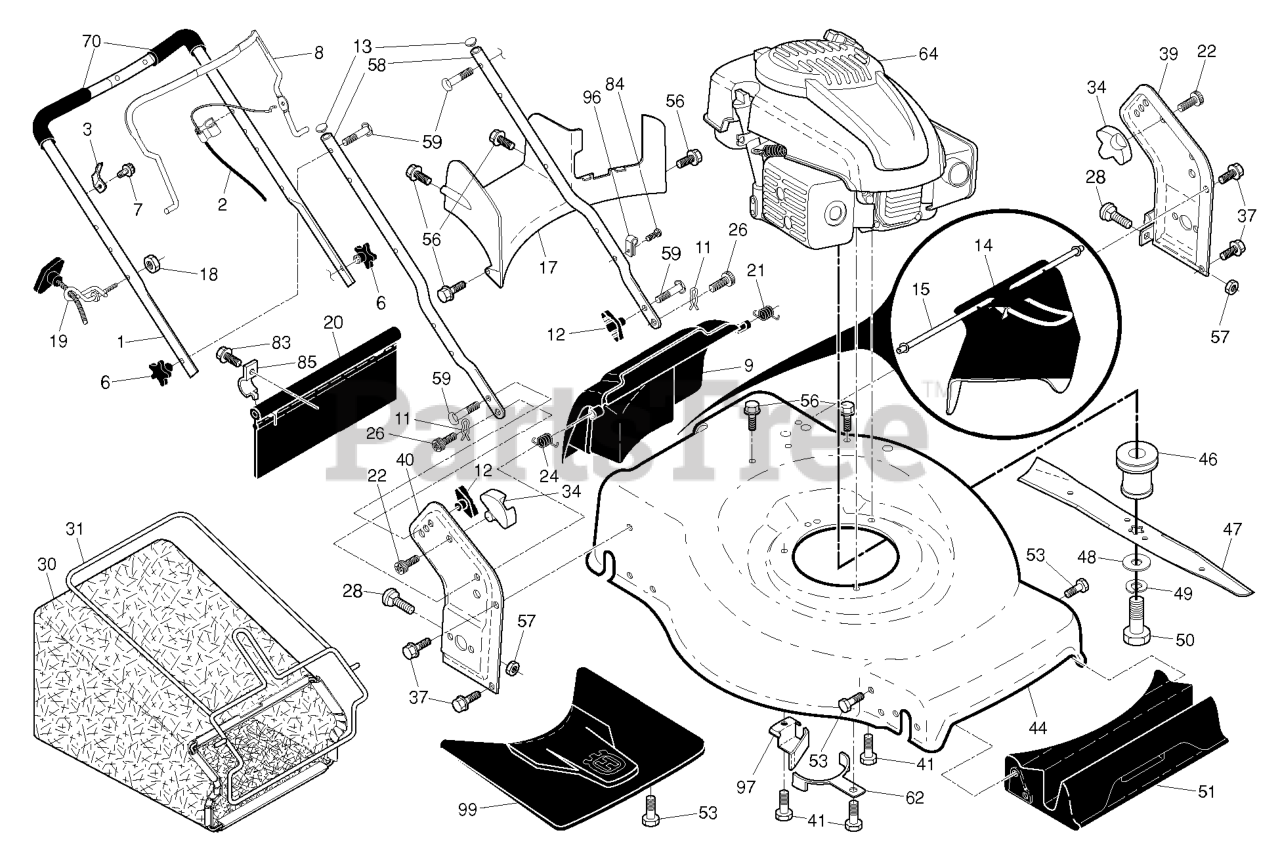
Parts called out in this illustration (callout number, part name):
1	HANDLE.ASM.GRY.W/GRIP
2	CABLE.MZR.RGD.KOHLER.STRT
3	BRACKET.UPSTOP.RT
6	KNOB.HANDLE.PLASTIC.STAR.BLACK
8	BAIL.MZR.EZ2.DSTR.22+.ORG.E
9	DOOR.REAR.ASM.22+.HUSQ.FG/RGD
11	COTTER.HAIRPIN.DOOR/HANDLE.PIV
12	KNOB.WING.PLASTIC.BLACK
12	HANDLE.KNOB.BLACK
13	PLUG.PLASTIC.7/8".14-20.GAUGE
14	DEFLECTOR.CHUTE.22+REAR
15	HANDLE DEFLECTOR.22+REAR
17	RP.BAFFLE.REAR.22+.RGD.PL
18	NUT
19	RB GUIDE.ROPE.STD.BLK.ZIN WSL
20	SKIRT.REAR.22PLUS.RGD.LW(2 2MC
21	SPRING.LH.BLACK
22	SCREW.PAN.HEAD.#10
24	SPRING.RH.GRAY
26	SCREW,DOOR/HANDLE.PIVOT
28	BOLT
30	GBAG.A3610247T.SILV.HUSWT.BLUE
31	RB FRAME.GBAG.22PLUS
34	BRACKET.GRASSBAG.ATTACHING.BLK
37	BOLT.5/16HEX.WHS.HD
39	BRACKET.HANDLE.LT.22+.W/DP.GRE
40	RP.BRACKET.ASM.HANDLE.RT.22+.
41	BOLT 3/8-16X1-1/8
44	HOUSING.22+.RWD.HD.WO/PORT.ORN
46	ADPTER.BLAD.25M.VS.22PLU.STAR
47	BLADE.22+.PREMIUM/PREC.FGD/RGD
48	WASHER,HARDEN
49	LOCKWASHER
50	SCREW, HEX HD 3/8-24 X 1-3/8
51	BAFFLE.FRONT.22PLUS.PLASTIC RP
53	SCREW.HI-LO.5/16 X.75
56	SCREW.HX.13X.750
57	NUT.FLANGE.5/16
58	HANDLE.LOWER.22+BT.2PC.GRY
59	BOLT, HANDLE 5/16-18X1.75
62	BRACKET.KEEPER.BELT
70	GRIP.HANDLE.FOAM.WIDE.(1 SIDE)
83	TAPPING SCREW
84	FASTENER.PUSH.O.250X0.783
85	BRACKET.SKIRT.22+.BZP
96	CLIP.CABLE.BLK
97	BRACKE.BELT.GUIDE.22+
99	COVER.ASM.FRONT.SHROUD.HUSQ.
